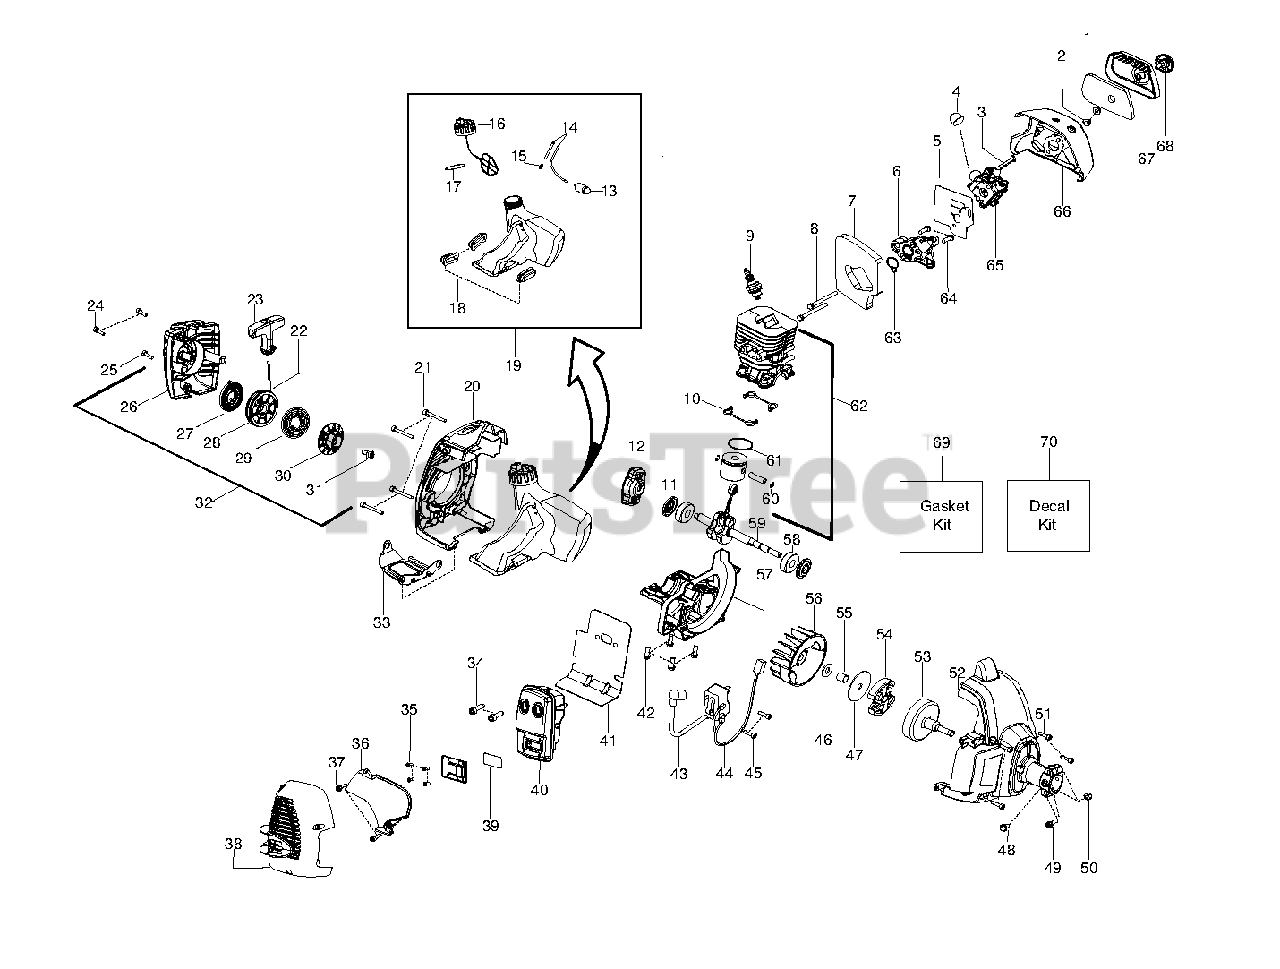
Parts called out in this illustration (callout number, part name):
1	FILTER AIRBOX
3	CHOKE LEVER
4	PURGE BULB ZAMA
5	KIT GASKET CARB 28CC
6	CARB ADAPTOR
7	KIT GASKET 28CC
8	BOLT CARB ADAPTOR
10	KIT GASKET 28CC
11	KIT GASKET 28CC
12	STARTER PAWL BRIDGE
13	FUEL PICK-UP ASSY
14	KIT-LINE(FUEL)
15	FUEL LINE FITTING
16	ASSY - FUEL CAP W/RETAINER
17	KIT GASKET 28CC
18	ISOLATOR FUEL TANK
19	KIT FUEL TANK ASSY
20	SHROUD REAR
23	HANDLE - STARTER
24	SCREW M5-0.8X30MM
25	SCREW M4 X 1.75 PT 16MM
26	STARTER HSG W/EYELET
27	KIT STARTER SPRING
28	KIT STARTER PULLEY
29	SPRING - DRIVER
30	DRIVER PULLEY
32	ASSY STARTER HSG
33	PLATE WEAR
34	BOLT MUFFLER
35	SCREW-6-19X5/16PLAST PA
36	SHIELD HEAT
37	SCREW M4 X 1.75 PT 16MM
38	KIT MUFFLER GUARD
39	KIT SPARK ARRESTOR SCREEN
40	KIT MUFFLER W/CATALYST
41	KIT GASKET 28CC
42	B0LT, C/SHAFT 36/41
43	IGNITION MODULE
44	ASSY MODULE LEAD WIRE
45	SCREW M4 X .70 TT 16MM
46	WASHER CLUTCH
47	WASHER-CLUTCH
48	SCREW-10-16 X 1/2, TYPE 2
49	SCREW-10-24 X 1" (UNC)
50	LOCKNUT-HEX 10-24
51	SCREW M4 X .70 TT 16MM
52	ASSY FAN HOUSING
53	ASSY-CLUTCH DRUM
54	ASSY CLUTCH
55	SPACER FLYWHEEL
57	CRANKCASE CAST LE28
58	BEARING RADIAL BALL (6201)
59	ASSY CRANKSHAFT
60	WRIST PIN RET.
61	RING PISTON
62	KIT PISTON & CYLINDER
63	KIT GASKET 28CC
64	B0LT, C/SHAFT 36/41
65	KIT CARB
66	AIRBOX BLACK
67	COVER AIR BOX
68	ASSY - AIR BOX KNOB
69	KIT GASKET 28CC
